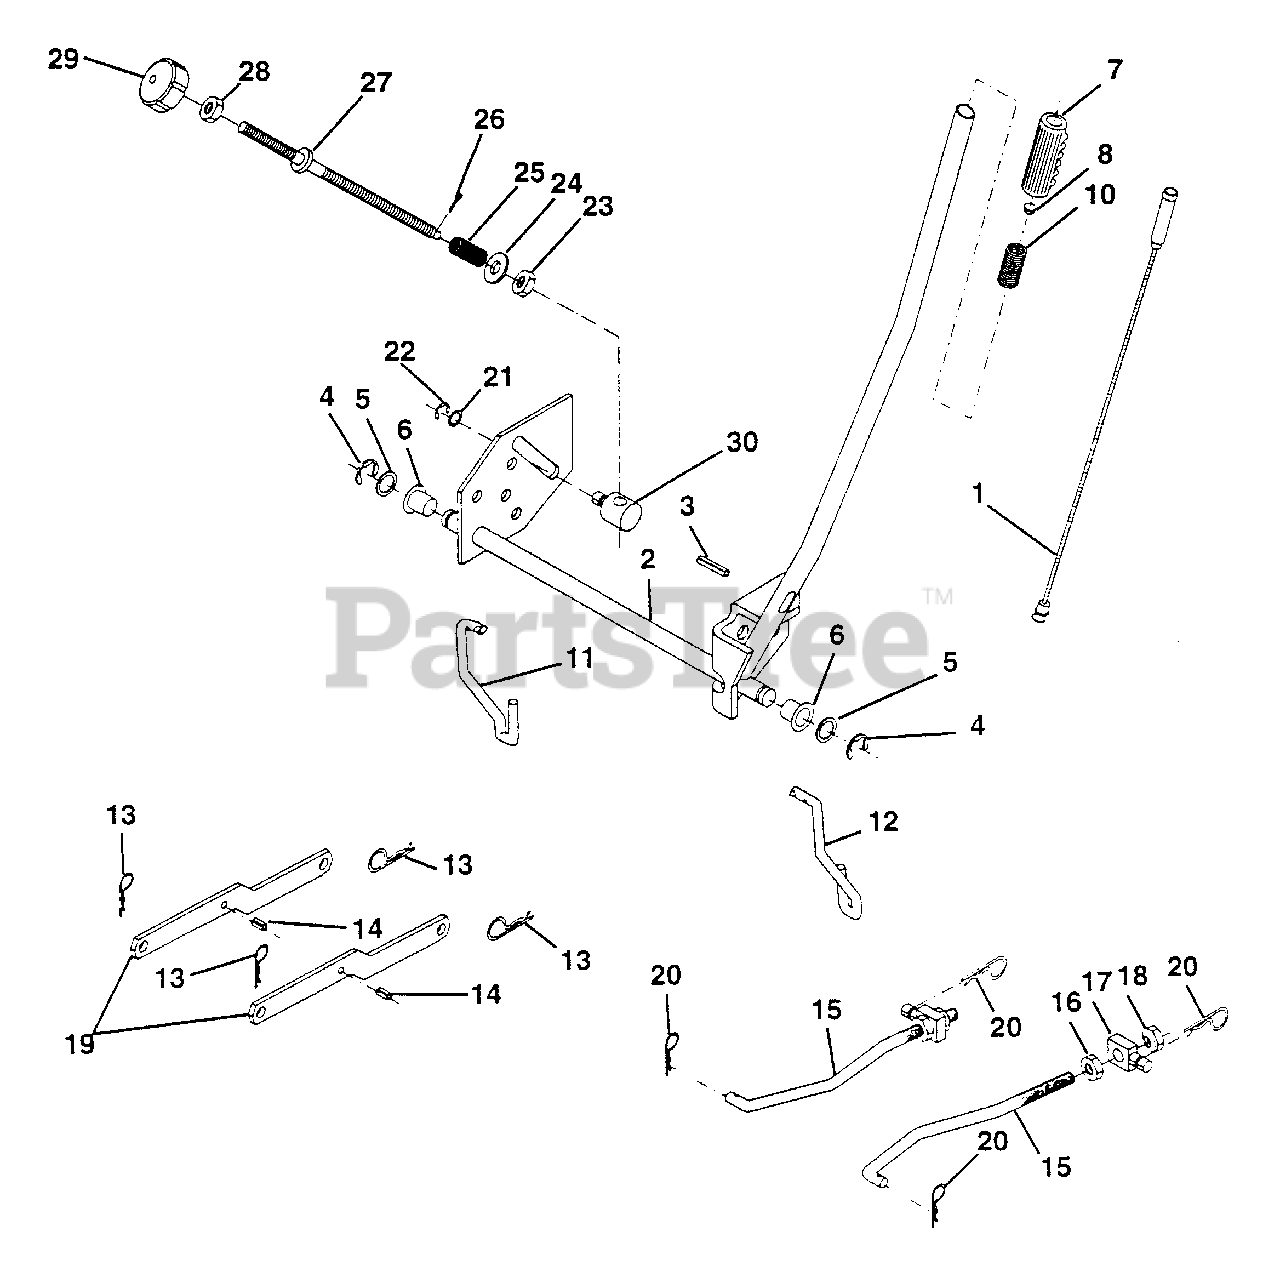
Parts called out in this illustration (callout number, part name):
1	Wire Asm Inner W/plunger 17 32
2	Shaft Asm Lift 93 RH
3	Pin Groove 1 500 Zinc
4	E Ring #5133-62
5	Washer 21/32 X 7/8 X 16 Ga
6	Bearing Nylon Blk 629 Id
7	Grip Handle Fluted Blk
8	Button Plunger Black
10	Spring Cprsn 3 750 Oiled
11	Link Lift LH Fixed Length
12	Link Lift RH Fixed Length
13	Retainer Spring
14	Pin Roll SLT 5/16 X 1 25 Blk 0
15	Link Front
16	Nut Jam Hex 1/2-13 Unc
17	Trunnion Blk Zinc
18	Nut Lock W/wsh 1/2-13unc
19	Arm Suspension Rear
20	Retainer Spring
21	Washer 15/32 X 3/4 X 16 Ga
22	Ring Klip #t5304-37
23	Nut Special
24	Washer 13/32 X 5/8 X 16 Ga
25	Spring 2-1/8"
26	Pin Cotter 3/32 X 1/2
27	Rod Adj Lift Zinc 9 00 Wrk Lg
28	Nut Hex Jam 3/8-16 Unc
29	Knob inf 3/8-16 Unc Blk W/sym
30	Trunnion Dp Stop Dbl Thds PLT
